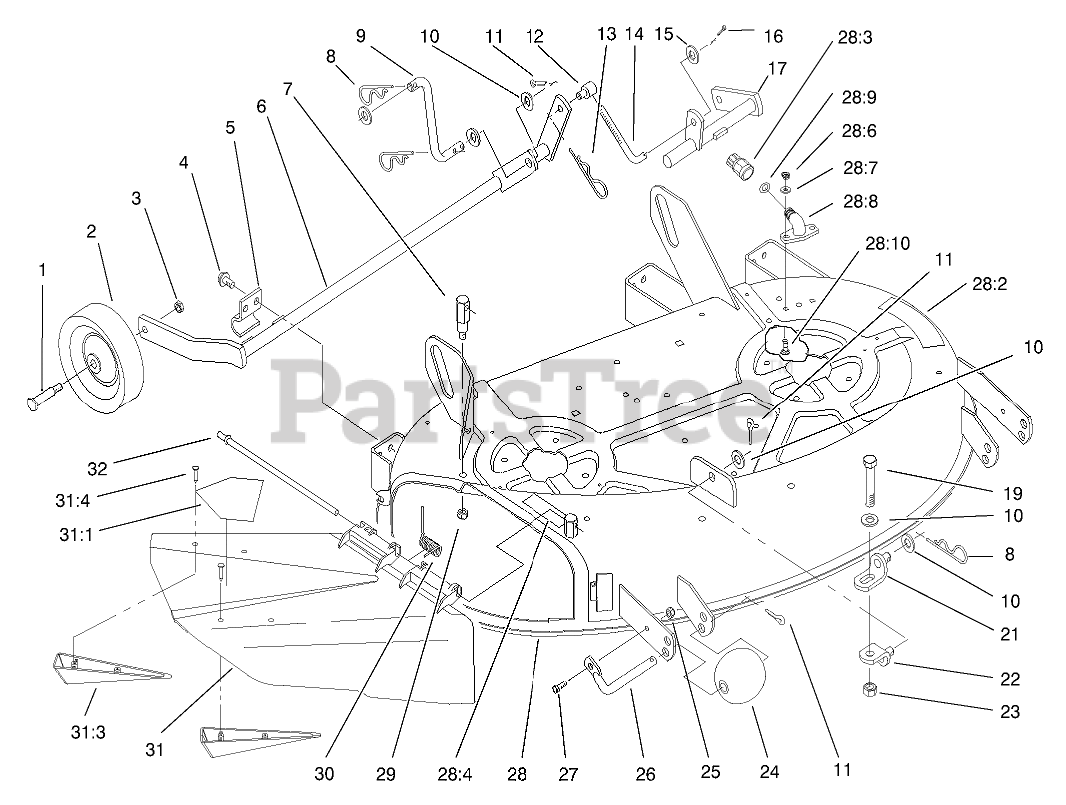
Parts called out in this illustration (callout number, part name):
1	BOLT-SHOULDER
2	WHEEL
3	NUT-HEX
4	SCREW-HWH, TAPTITE
6	SHAFT-RH
7	PIVOT POST - REAR
8	PIN-COTTER, HAIR
9	LINK-REAR
10	WASHER-FLAT
11	PIN-COTTER
12	TRUNNION
13	PIN-HAIR
14	ROD-LIFT
15	WASHER-FLAT
16	PIN-COTTER
17	SHAFT-LH
19	SCREW-HH
21	BRACKET-LIFT, LOWER
22	BRACKET-LIFT, UPPER
23	NUT-JAM
24	ROLLER
25	NUT-LOCK, NI
26	Shaft-Roller
27	SCREW-HH
28	DECK ASM
28:2	DECAL-DANGER
28:3	CONNECTOR-HOSE
28:4	DECAL-CAUTION
28:6	NUT-LOCK, NI
28:7	WASHER-FLAT
28:8	FITTING-WASHOUT
28:9	O-RING
28:10	BOLT-CARR
29	NUT-LOCK, NI
30	SPRING
31	DEFLECTOR ASM
31:1	DECAL-DANGER
31:3	KICKER
31:4	SCREW-PPH
32	ROD-HINGE DEFLECTOR
